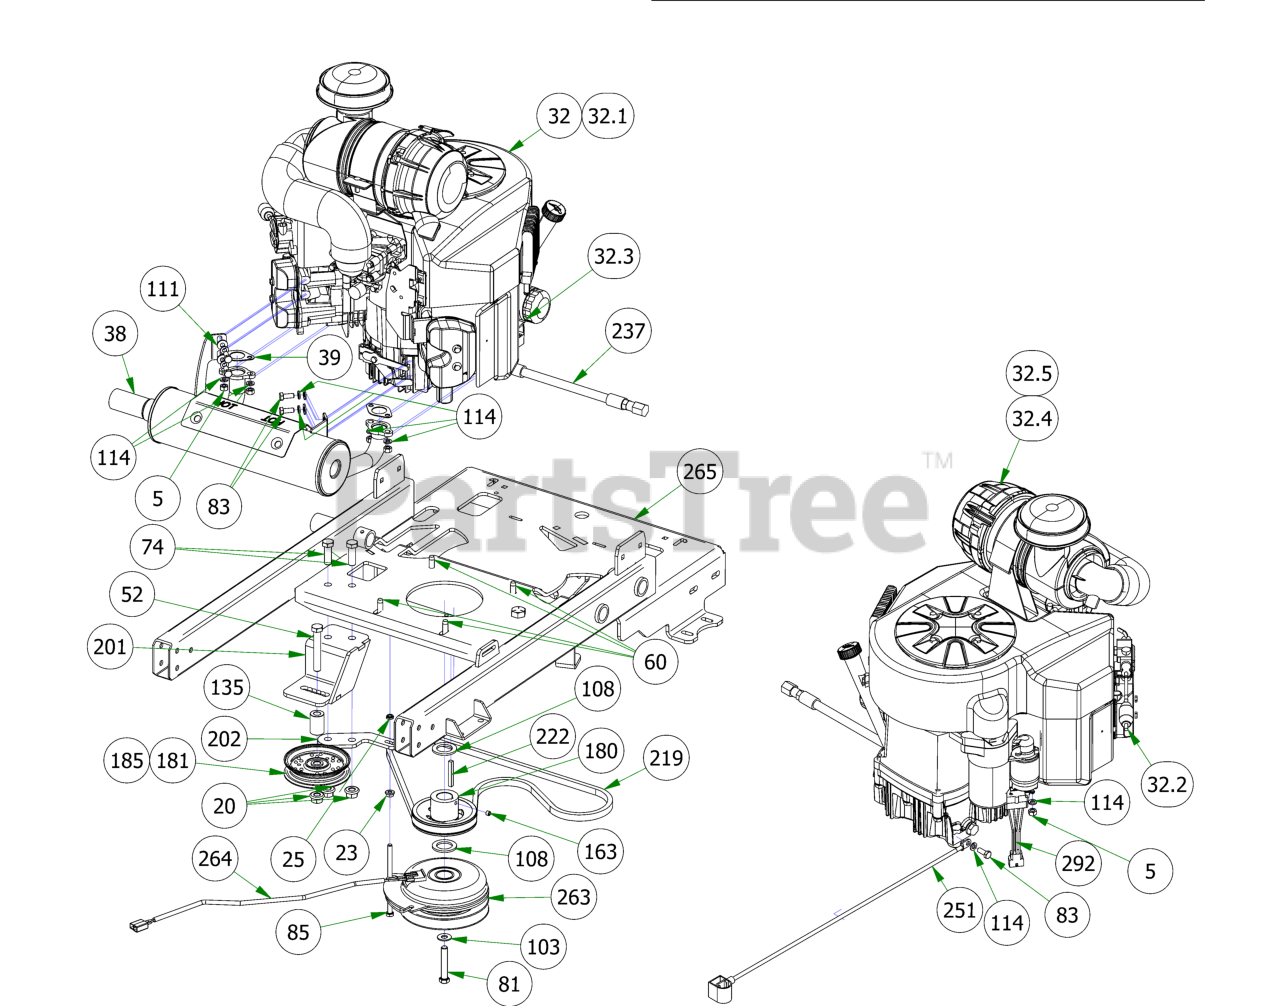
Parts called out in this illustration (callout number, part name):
5	M8-1.25 DIN 934 HEX NUT (CL.8) ZINC
20	1/2-13 NYLON INSERT FLANGE LOCKNUT ZINC
23	5/16-18 HEX SERRATED FLANGE NUT HARD/ZINC
25	5/16-18 NYLON INSERT JAM LOCKNUT ZINC
32	Kawasaki FX850 Engine
32.1	Spark Plug - Kawasaki
32.2	Universal Inline Fuel Filter
32.3	Oil Filter
32.4	Canister Air Filter- Outer
32.5	Canister Air Filter- Inner
38	Revolt Kawasaki FX850 Exhaust
39	Exhaust Gasket
52	1/2-13 X 3-1/4 HEX CAP SCREW (GR.5) ZINC
60	3/8-16 X 1-1/8HEX WASHER UNSLOT SERRATED (TRI-LOB) TRS
74	1/2-13 X 1-1/2 HEX CAP SCREW (GR.5) ZINC
81	7/16-20 X 2-1/2 HEX CAP SCREW (GR.8) ZINC YELLOW
83	M8-1.25 X 20MM DIN 933 HEX TAP BOLT (CL 8.8) ZINC
85	5/16-18 X 5-1/2 HEX CAP SCREW (GR.5) ZINC
103	3/8 FLAT WASHER USS (1" OD) ZINC
108	1.140 ID X 1.750 OD X .132 THICK FLAT WASHER PLAIN
111	1/4 USS FLAT WASHER (3/4 OD) ZINC
114	5/16 SPLIT LOCKWASHER ZINC
135	.502 ID X .750 OD X 1.500 Long Spacer
163	5/16-24 X 1/4 SOCKET SET SCREW (CUP PT) PLAIN
180	4 3/4 Motor Pulley
181	4 3/4 Idler Pulley - ABFI-76
185	5-3/4 Idler Pulley
201	Idler Pulley Bracket Weldment 2019 Stand On
202	2019 Stand On Clutch Stop Bracket
219	2019 Stand On Pump Belt (Timken# 47-2827)
222	1/4 X 2 SQ MACHINERY KEY 1018 STL PLAIN
237	Kawasaki Oil Drain
251	24 inch Black Cable – MZ/ZT
263	Clutch Assembly
264	Clutch Pigtail
265	2019 Stand On Frame
292	2019 Harness Adaptor-Gen2 FX-ALL
